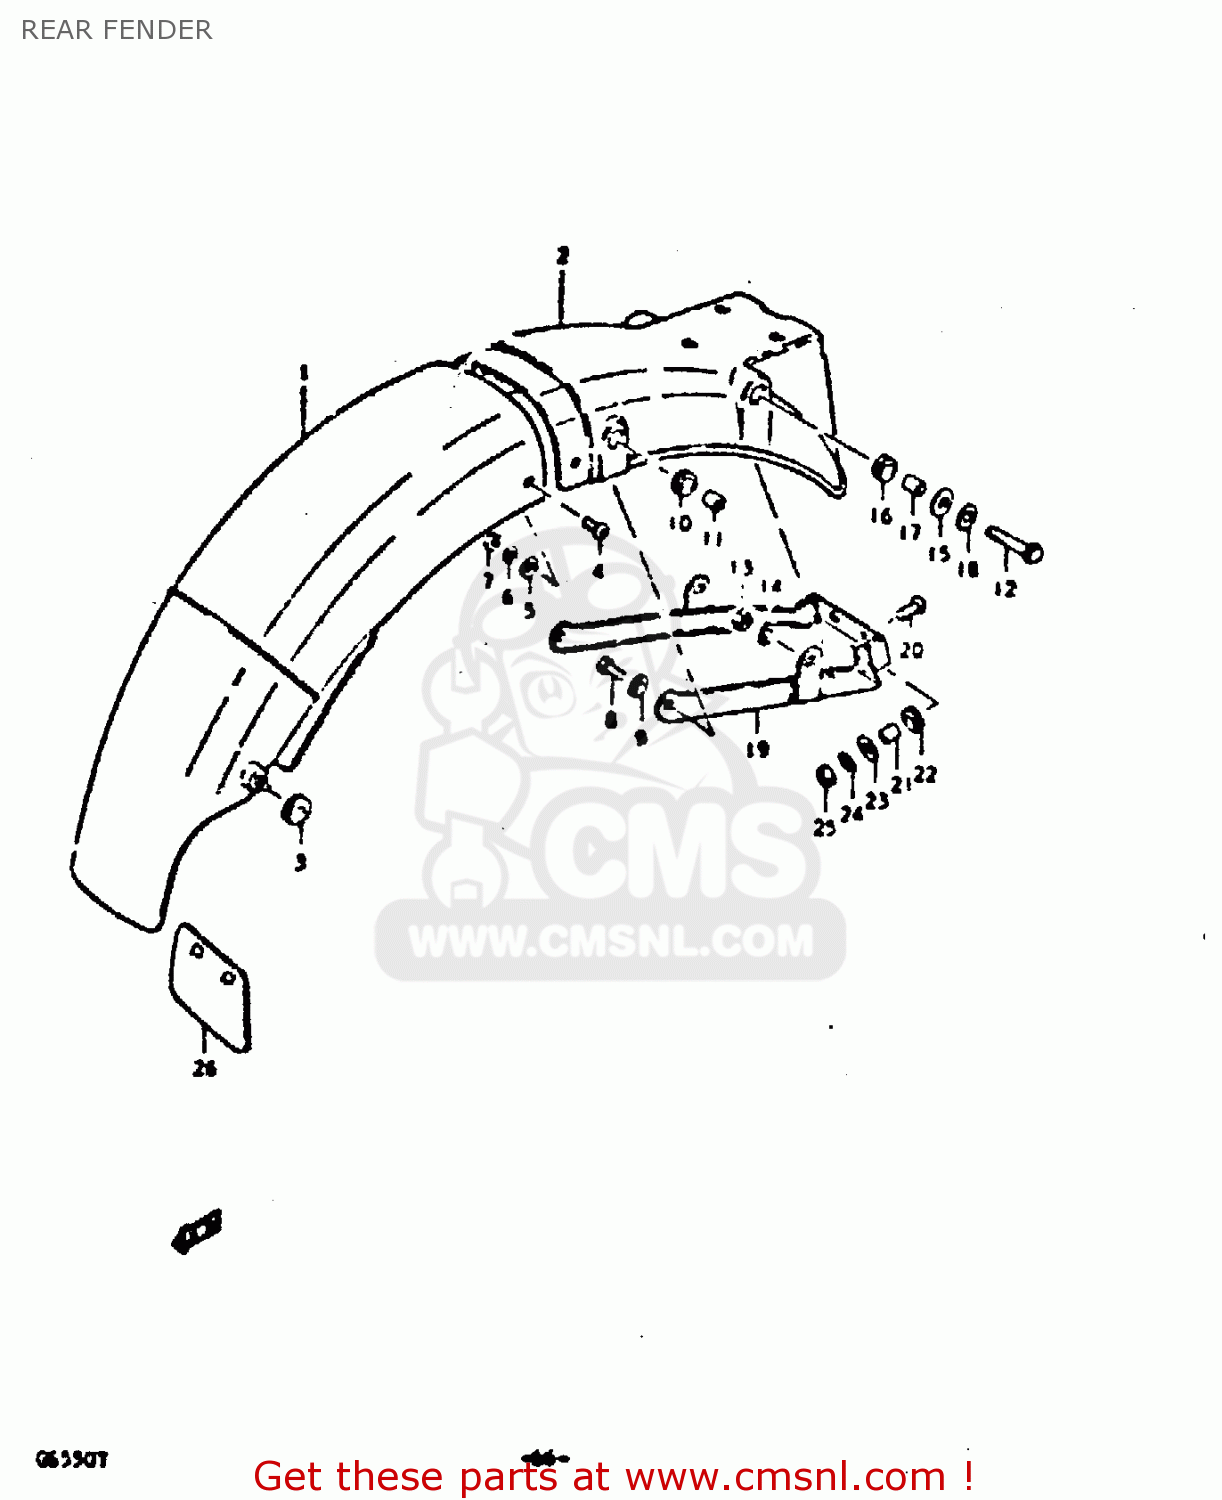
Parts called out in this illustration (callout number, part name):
1	FENDER,REAR
2	BODY,REAR FENDER,REAR
3	CUSHION
4	SCREW
5	WASHER (5.5X16X1.2)
6	LOCK WASHER
7	NUT
8	BOLT
9	LOCK WASHER
10	CUSHION
11	SPACER(6.1X9X7.5)
12	BOLT
13	NUT
14	LOCK WASHER
15	WASHER(8.5X26X1.2)
16	CUSHION
17	SPACER (8.2X12X7.5)
18	WASHER
19	REINFORCEMENT,REAR FENDER
20	SCREW
21	SPACER (6.1X9X9)
22	CUSHION
23	WASHER(6,5X22X1.6)
24	LOCK WASHER
25	NUT
26	GUIDE,RR FENDER MUD
